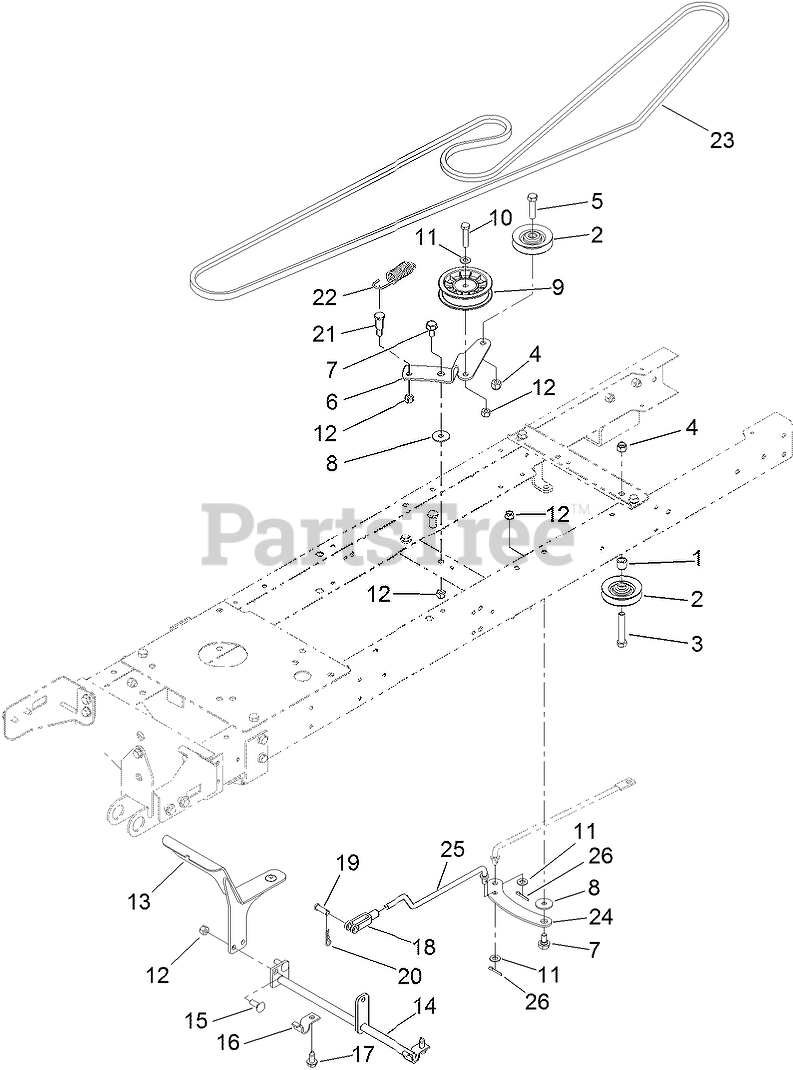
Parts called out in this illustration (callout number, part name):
1	BUSHING-LEVER, LIFT
2	PULLEY-IDLER
3	SCREW-HH
4	NUT-LOCK, NI
5	SCREW-HH
6	BRACKET-IDLER
7	BOLT-SHOULDER
8	WASHER-PIVOT
9	PULLEY-IDLER
10	SCREW-HH
11	WASHER-PLAIN
12	NUT-LOCK, NI
13	PEDAL-CONTROL, MOTION
14	SHAFT-CONTROL, MOTION
15	SCREW-CARR
16	CLAMP-PIVOT, SHIFT
17	SCREW-HWH
18	YOKE-ADJUSTABLE
19	PIN-CLEVIS
20	PIN-COTTER
21	SCREW-SHOULDER
22	SPRING-EXTENSION
23	BELT-DRIVE, BLADE
24	BRACKET-TRACTION, LINK ARM
25	ROD-MOTION CONTROL, FRONT
26	PIN-COTTER
